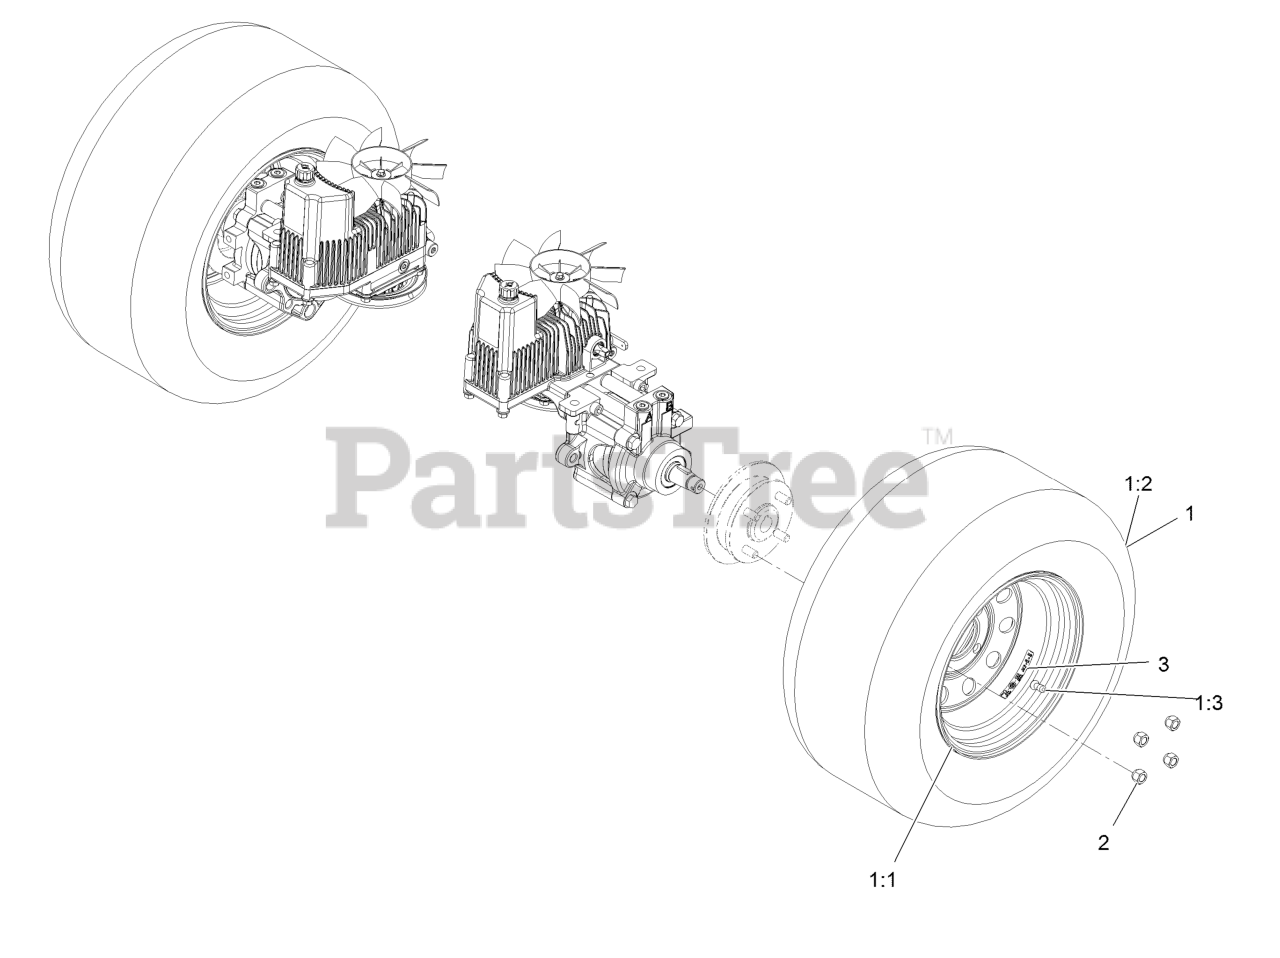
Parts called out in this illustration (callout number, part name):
1	ASM-Wheel And Tire
1:1	ASM-Rim 60
1:2	Tire-Drive
1:3	Stem-Valve
2	Nut-Lug 1/2-20
3	Decal-Torque, Wheel Hub Lug
